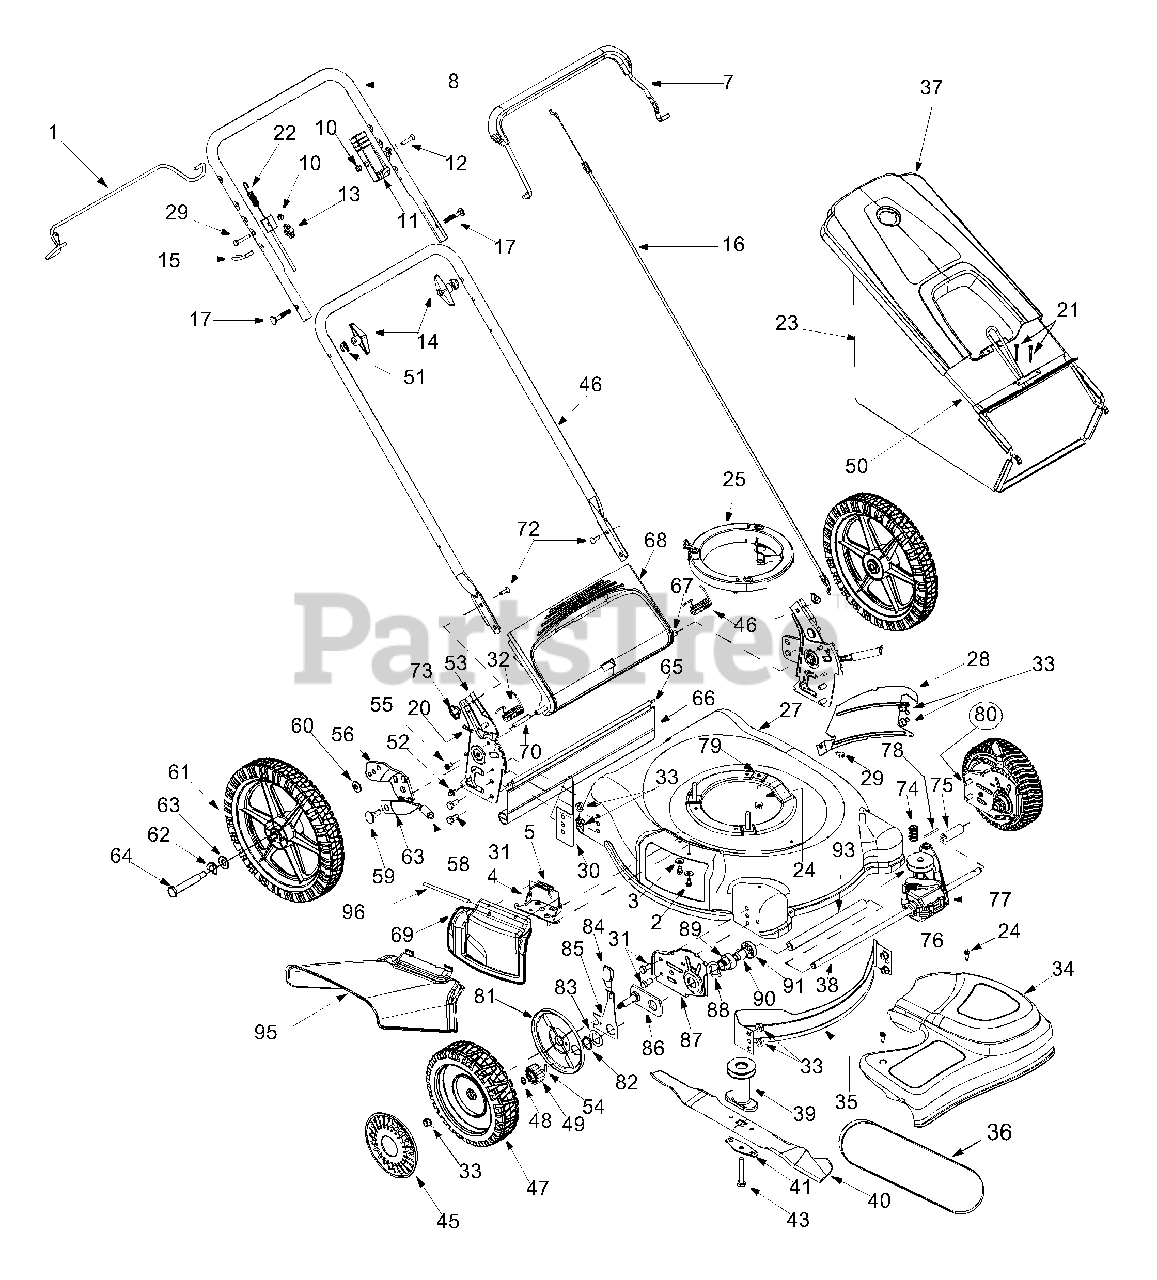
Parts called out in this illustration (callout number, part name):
2	TT Screw 1/4-20 x 0.5
3	Bell Washer .265 x 0.75
4	Hinged Mounting Bracket
5	Torsion Spring
7	Control Lever Deluxe
10	Hex Lock Nut, 1/4-20
11	Control Housing
12	Oval C-Sunk Screw 1/4-20 x 1.31
13	Handle Knob
14	Handle Knob
15	Eye Bolt
16	Control Cable:39"
17	Carriage Bolt 5/16-18 x 2.0
20	Cotter Pin
21	Self-Tapping Sems Screw
22	Drive Cable
23	Grassbag Assembly
24	TT-Tap Screw 3/8-16
25	Engine Spacer
29	Screw AB: 1/4-14: .625
31	Hex Screw 3/8-16 x .75
32	Torsion Spring
33	Hex Nut 3/8-16
34	Transmission Cover
37	Grassbag Hardtop Cover
38	Axle: Front
39	Blade Adapter w/ Pulley
40	21" Mulching Blade
41	Blade Bell Support
43	Hex Screw 3/8-24 x 2.50
45	Hub Cap
46	Torsion Spring
47	Wheel Zag Tread 8 x 2
48	Snap Ring
49	Gear 14T LH FWD
51	Saddle Washer
52	Hex Scr. w/Washer 1/4-14 x .625
53	RH Handle Bracket
54	Dowel Pin
55	Pan Head Screw
56	RH Pivot Bar
58	Foam Grip
59	Shoulder Scr .500 Dia. x .434
60	Washer .401 x .870 x .063
61	Wheel, 14 x 2 Zag Tread
62	Spring Washer .50 I.D. x 1.0 O.D.
63	Flat Washer
64	Shoulder Screw
65	Wire
66	Rear Trailing Shield
67	Pivot Rod
68	Rear Discharge Door
69	Mulch Plug Complete
70	Spacer .375 x .50 x 1.02" Lg.
72	Carriage Bolt 1/4-20
73	Wing Nut
74	Belt Tension Spring
75	Slev. Spacer 2.1" LG
76	Input Pulley
77	Transmission Assembly
78	Roll Pin
79	Self Tapping Screw, 5/16-18
80	Height Adjustment Assembly RH
81	Wheel Dust Cap
82	Snap Ring
83	Washer
84	Adjustment Knob
85	Front Lever RH
86	Pivot Plate Assembly
89	Bearing Support
90	Bearing Sleeve
91	Bearing Retainer
93	Sleeve Spacer 8.9" LG
95	Chute Deflector
96	Hinge Pin
